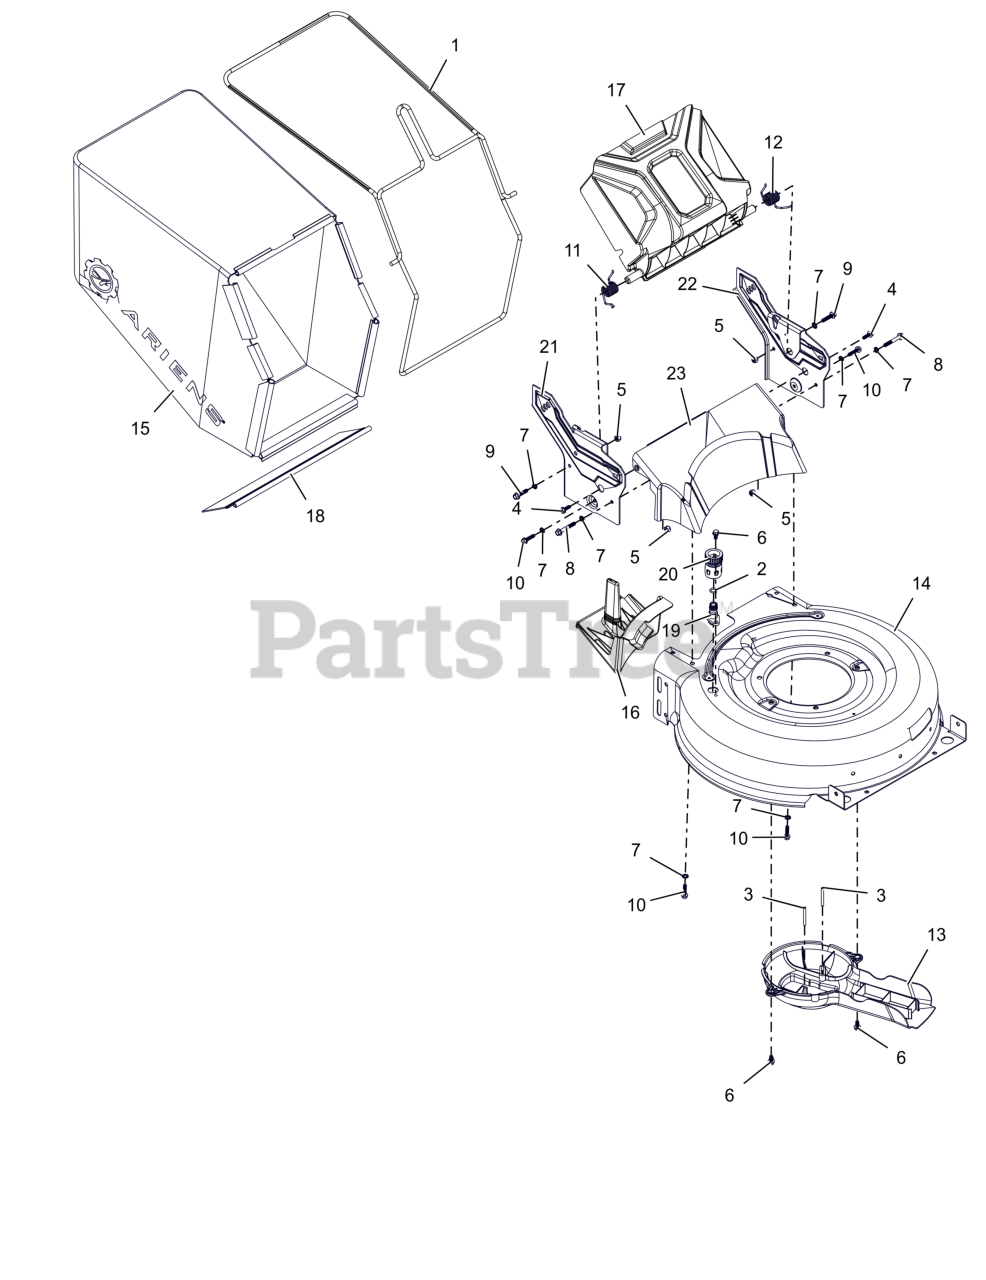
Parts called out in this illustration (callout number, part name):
1	WLDMT, BAG FRAME (ORANGE)
2	O-RING, OD .625 ID .425
3	PIN, .188 X 1.750
4	SCR, HI-LO HWH 1/4-15 X .750
5	NUT, NYLOC 1/4-20
6	SCR, 1/4-20X.500, THREAD FORMING
7	WSHR-LK-EXT, .256X.510X.028
8	BLT, HEX 1/4-20 X 1.75 GR5
9	BLT, HEX 1/4-20 X 1.125
10	SCR, HI-LO HWH 1/4-15 X 1.00
11	SPRG, TORSION - DOOR LH
12	SPRG, TORSION - DOOR RH
13	COVER, FWD PULLEY
14	DECK, FWD -21 (WO PORT) (ORANGE)
15	BAG, ARIENS
16	PLUG, MULCH
17	DOOR, REAR
18	GUARD, REAR DECK
19	ADAPTOR, DECK WASH OUT
20	CONNECTOR, QUICK DISCONNECT
21	BRKT, RH SIDE (BLACK)
22	BRKT, LH SIDE (BLACK)
23	COVER, BACK - FWD
